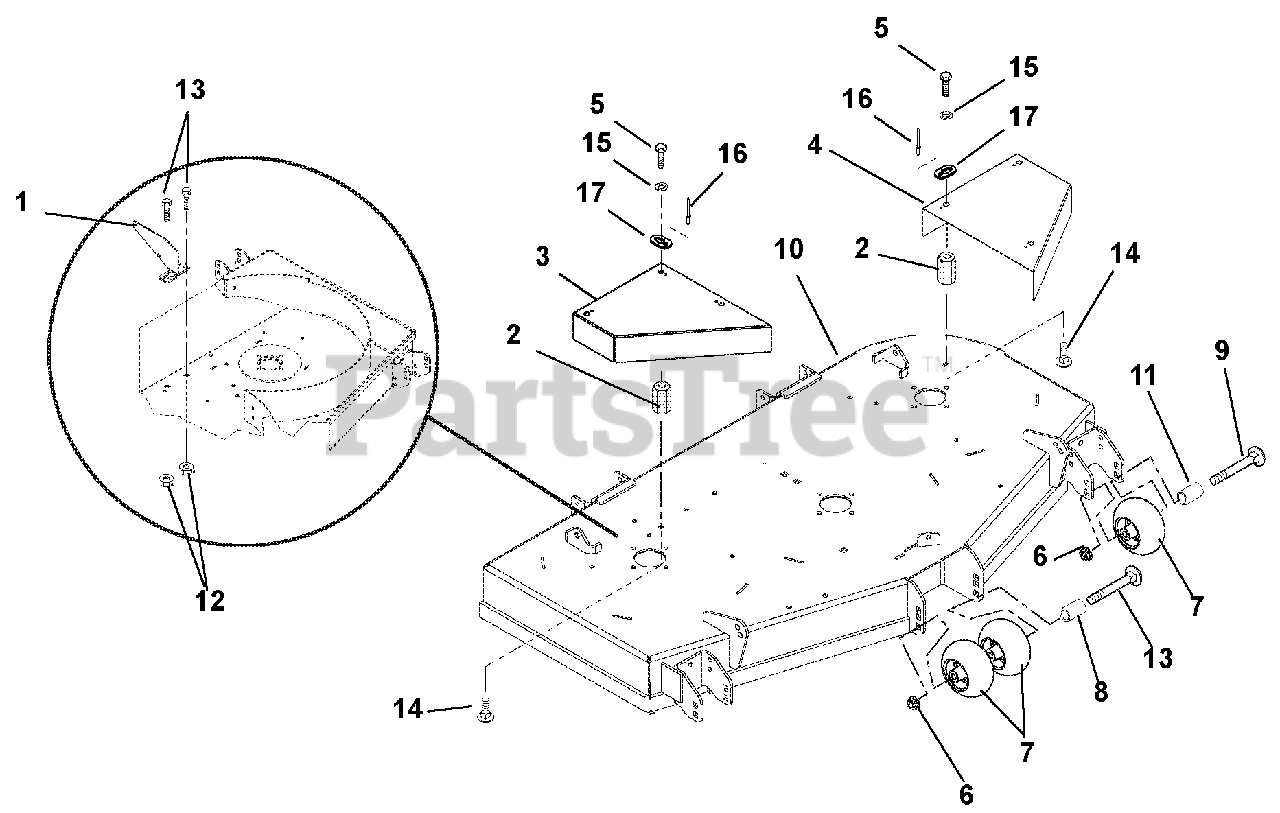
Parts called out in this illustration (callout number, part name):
1	Rear Deflector Baffle
2	Nut, Coupling, .31-18/.38-16 x 3.00
3	Guard, 52-in. Right Hand Spindle Sheave (922322)
4	Guard, 52-in. Left Hand Spindle Sheave (922322)
5	Bolt, Hex .38-16 x 1.25 Grade 5 Captive
6	Nut .50-13 Nyloc Flange
7	Anti-Scalp Wheel
9	Bolt, Round Head Square Neck .50-13 x 5.00
10	52-in. Mower Deck (922322)
11	Spacer, .510 x .625 x 3.35
12	Nut, .38-16 Nyloc Flange
13	Bolt, Round Head Square Neck, 3/8-16 x 1.00
14	Bolt, Round Head Square Neck, .31-18 x .75 Loc-Tite®
15	Washer, Lock External, .391 x .682 x .036
16	Rivet, Pop, .187 YZ (IFI 114 GR. 30) Actual Grip
17	Keeper, Bolt
